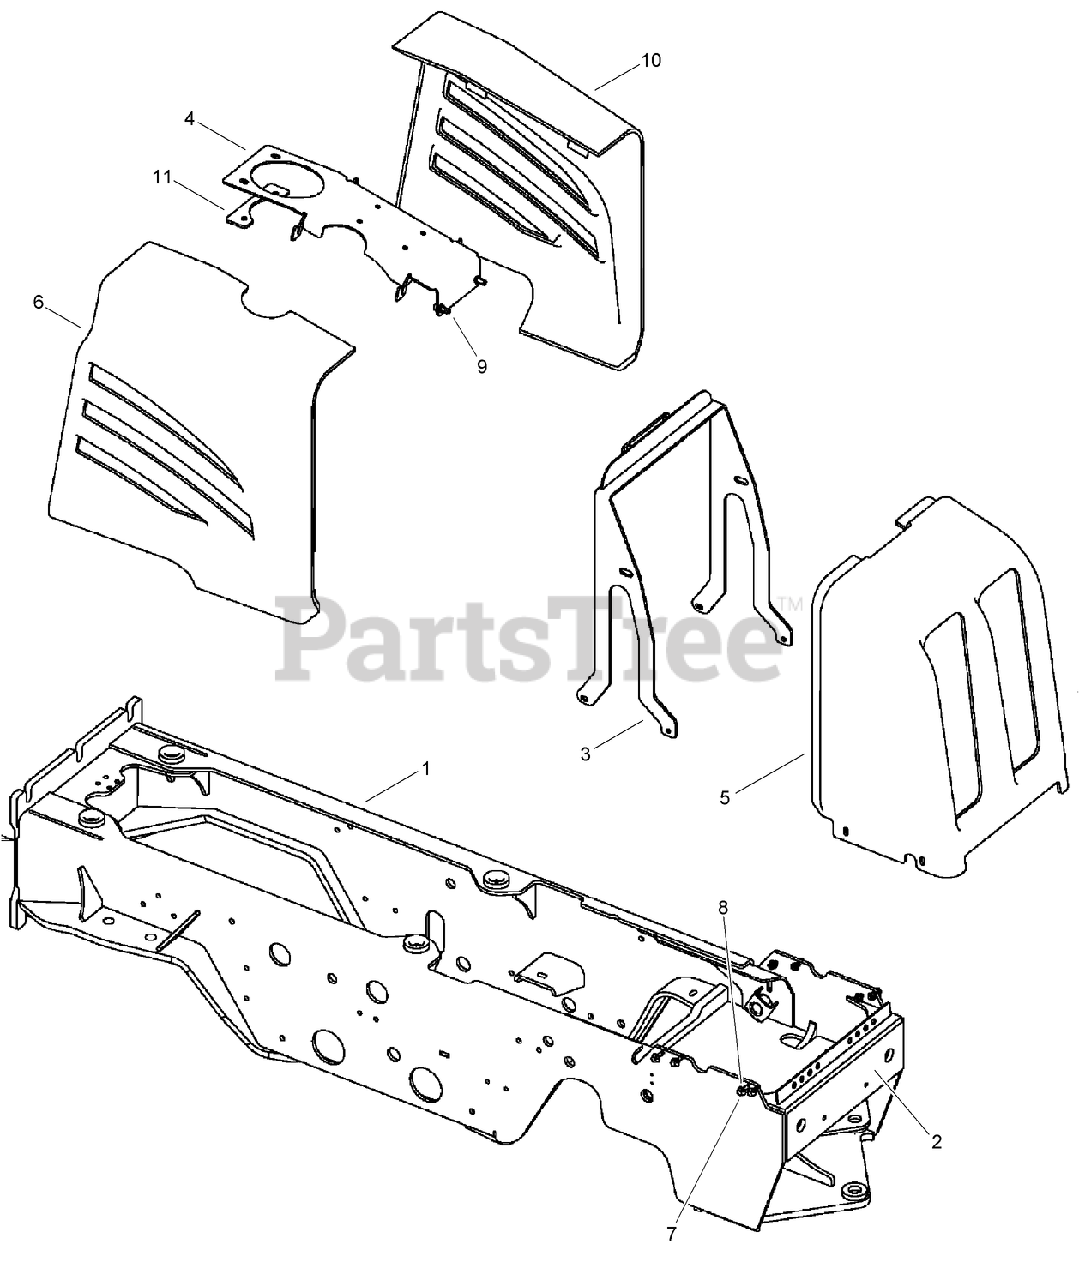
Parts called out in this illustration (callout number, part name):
1	WELDMENT-Chassis
3	ASM-Hood Support
4	WELDMENT-Hood Support Plate
5	CLIP-Nose
6	HOOD-RH
7	SCREW-HH
8	NUT-FLANGE, NYLOCK
9	SCREW, METRIC FLANGE w/BODY-M12 x 30
10	HOOD-LH
11	PLATE-Spacer
